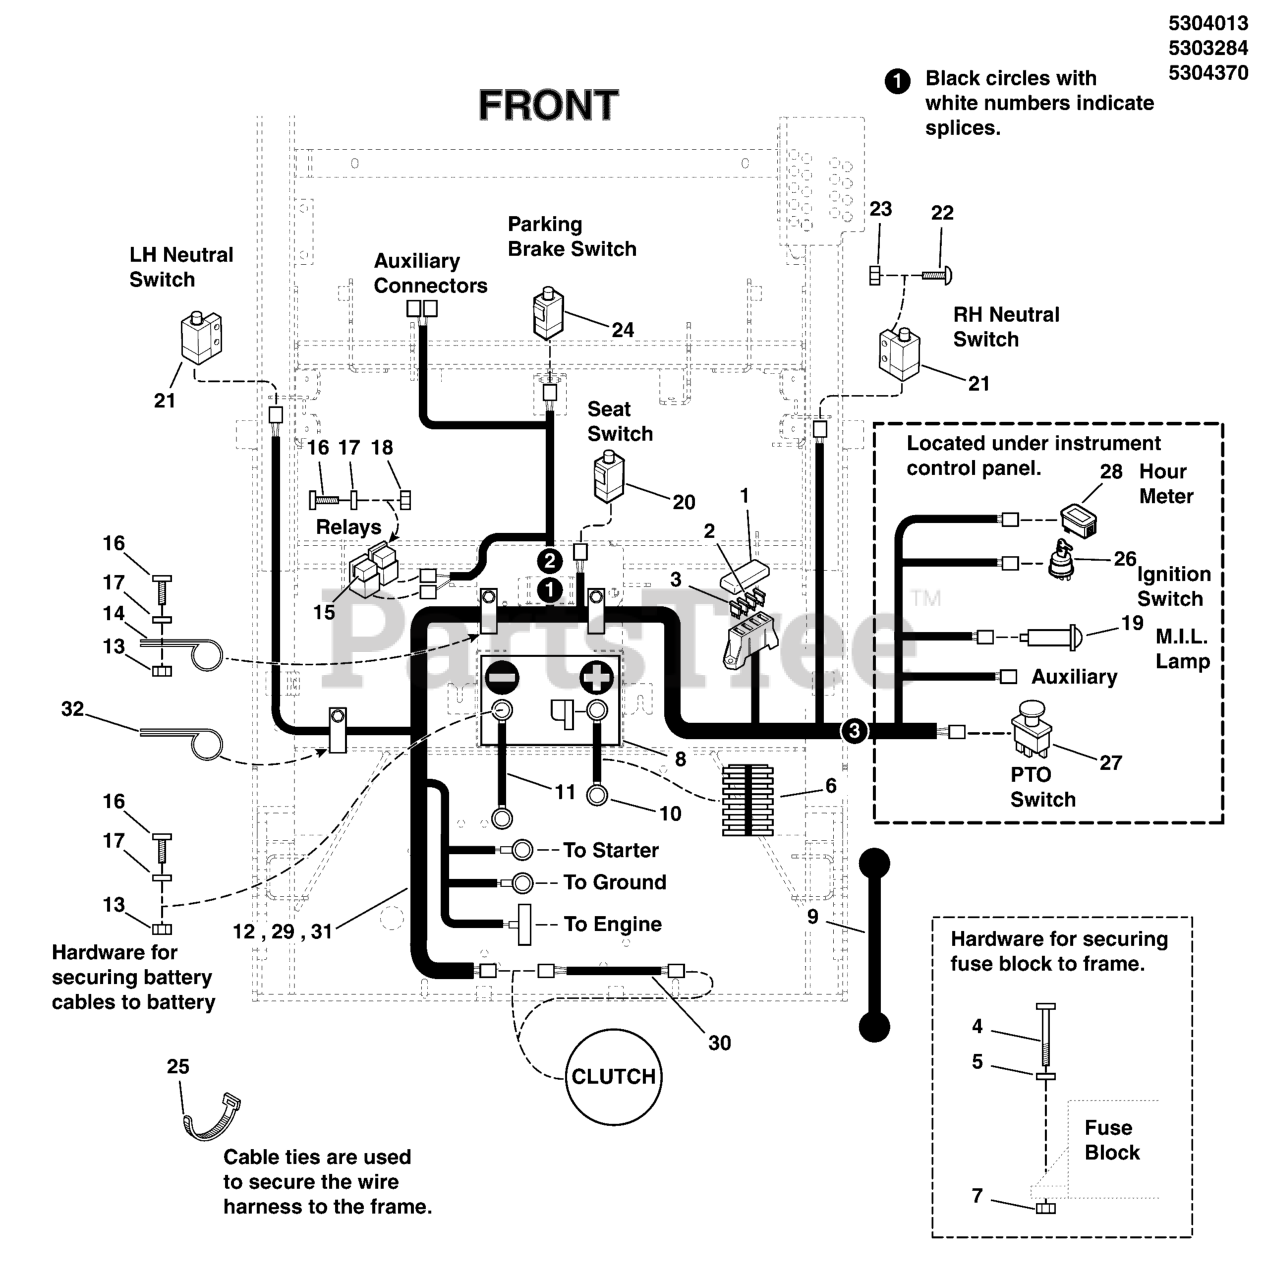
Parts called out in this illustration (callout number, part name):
1	COVER, VINYL FUSEBLOCK
2	FUSE, ATO-15 (15 AMP)(SV)
3	FUSE, ATO-20 (20 AMP)(SV)
4	SCREW, #10-24 X 2 ROUND PHILLIPS
5	WASHER, #10 SAE
6	WIRE LOOM, 3/8 ID X 17 IN
7	NUT, #10-24 HEX NYLON LOCK
8	BATTERY, 11U1L, 350 CCA
9	STRAP-BLACK RUBB
10	BATTERY CABLE, NEG, 14, 5/16-13/32
11	BATTERY CABLE, POS, 22, 1/4-5/16
12	WIRE HARNESS, S200XT, B&S EFI
13	NUT, 1/4-20 HEX NYLOCK FLANGE
14	CLAMP, VINYL INSULATED
15	RELAY, 12V, 40A
16	BOLT, 1/4-20 X 3/4 GD5 CZ
17	WASHER, 1/4 SAE
18	NUT, 1/4-20 HEX SERR. FLANGE
19	LAMP, MALFUNCTION INDICATOR LAMP (M.I.L.) (SEE INSTRUMENT CONTROL PANEL GROUP)
20	SWITCH, PLUNGER, NO/NO SNAP-IN
21	SWITCH, PLUNGER, N.O.
22	SCREW, #10-24 X 3/4 ROUND PHILLIPS
23	NUT, #10-24 HEX
24	SWITCH, DP NO/NC SNAP-IN
25	TIE, SELF-LOCKING, 12"
26	SWITCH, IGNITION, 6 POST (SEE INSTRUMENT CONTROL PANEL GROUP)
27	SWITCH, BLADE ENGAGEMENT (SEE INSTRUMENT CONTROL PANEL GROUP)
28	HOUR METER (SEE INSTRUMENT CONTROL PANEL GROUP)
29	WIRE HARNESS, S200XT KOHLER EFI
30	CLUTCH JUMPER W/DIODE, WARNER
31	WIRE HARNESS, S200XT B&S EFI, 37
32	CLAMP, VINYL INSULATED, .625
